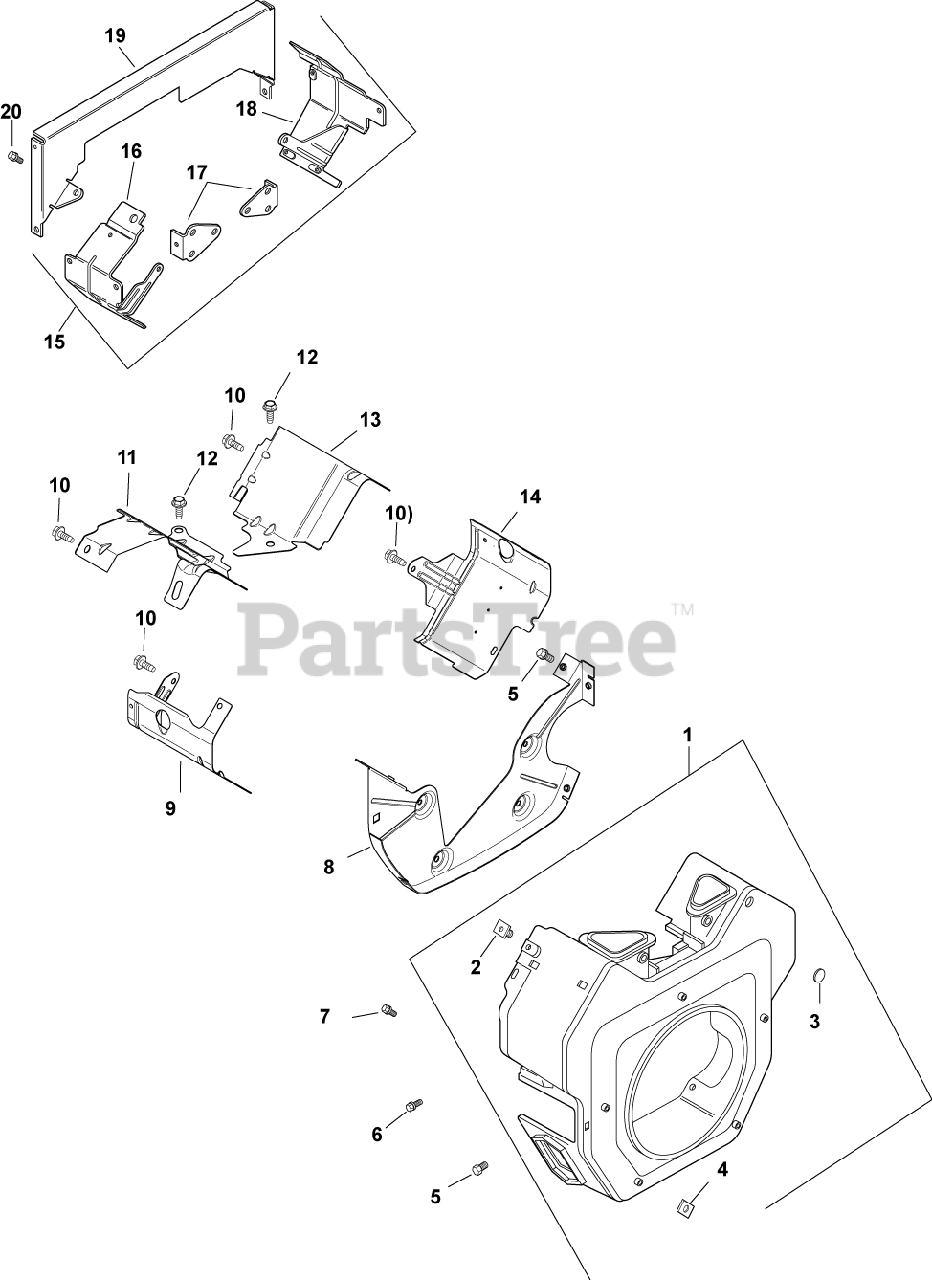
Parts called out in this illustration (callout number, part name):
1	KIT, BLOWER HOUSING ASSY-(#24027488S)
2	NUT, PLASTIC
3	PLUG, BUTTON 9/16
4	NUT, PLASTIC - BLACK
5	SCREW,FLG THD FRM M6X1.0X16-(#25086397S)
6	SCREW - USE M-545016-S
7	SCREW,FLG THD FRM M5X0.8X16-(#25086398S)
8	PLATE, BACKING-USE 24 146 59-S
9	BAFFLE, VALLEY #2 SIDE-USE 24 063 94-S
10	SCREW, FLG THD FRM M5X.8X20-(#25086399S)
11	BAFFLE, VALLEY (CH)-USE 24 063 93-S
12	SCREW, FLG THD FRM M5X.8X10
13	KIT, CYL BAFFEL #2 SIDE
14	KIT, CYL BAFFEL #1 SIDE
15	KIT, "Q"DUCT"
16	BAFFLE, DUCTED AIR-OIL FILTER
18	BAFFLE, DUCTED AIR-STARTER
19	PLATE, BACKING
20	SCREW, FLG M6X1.0X10
